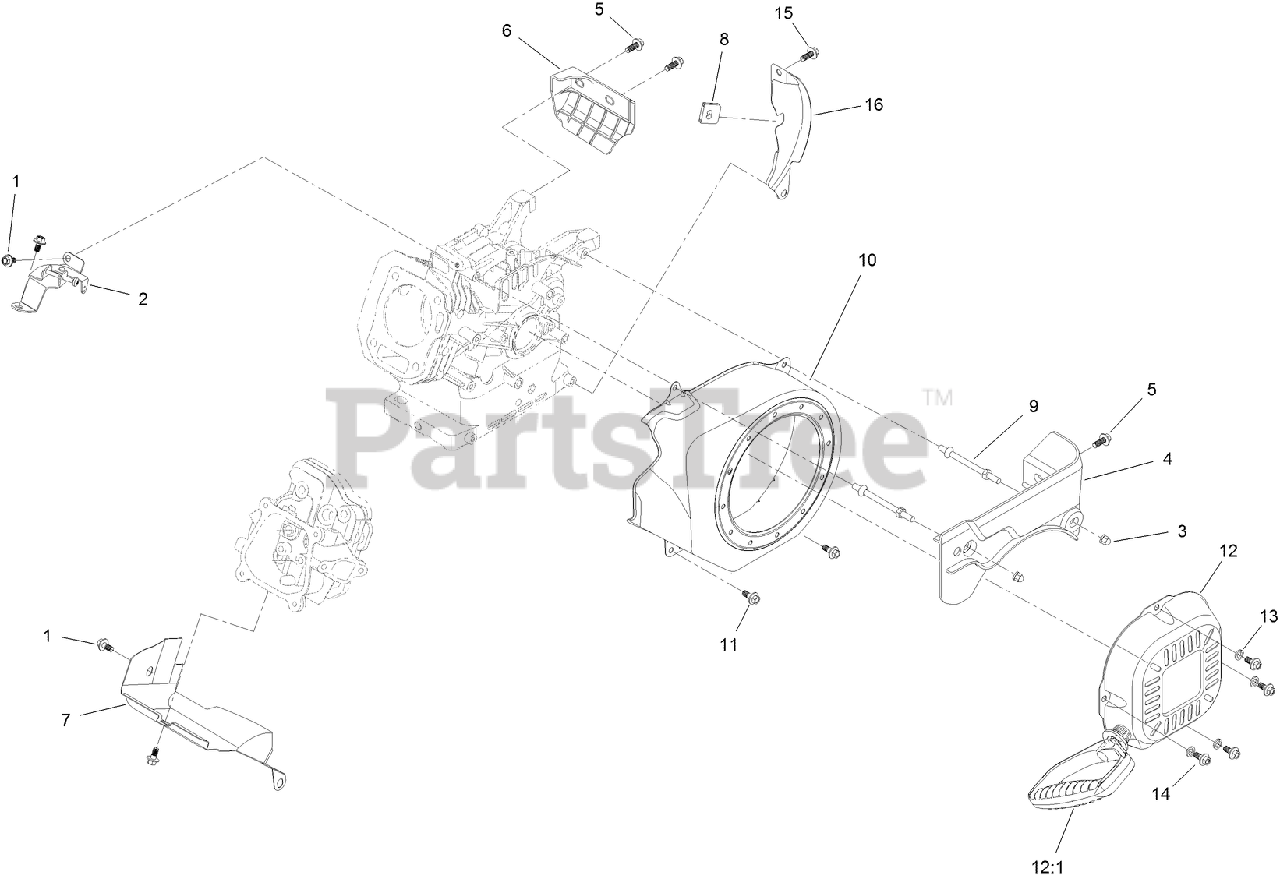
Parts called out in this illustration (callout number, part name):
1	SCREW-HHF
2	SPEED CONTROL ASM
3	NUT-ACORN
4	PANEL-FRONT
5	SCREW-HHF
6	PANEL-SIDE, ENGINE
7	SHROUD-LOWER
8	GROMMET-RUBBER
9	STUD-MOUNT
10	SHROUD-BLOWER
11	SCREW-HHF
12	RECOIL STARTER ASM
12:1	HANDLE-RECOIL
13	WASHER-PLAIN
14	SCREW-HHF
15	SCREW-HHF
16	SHIELD-FLYWHEEL
